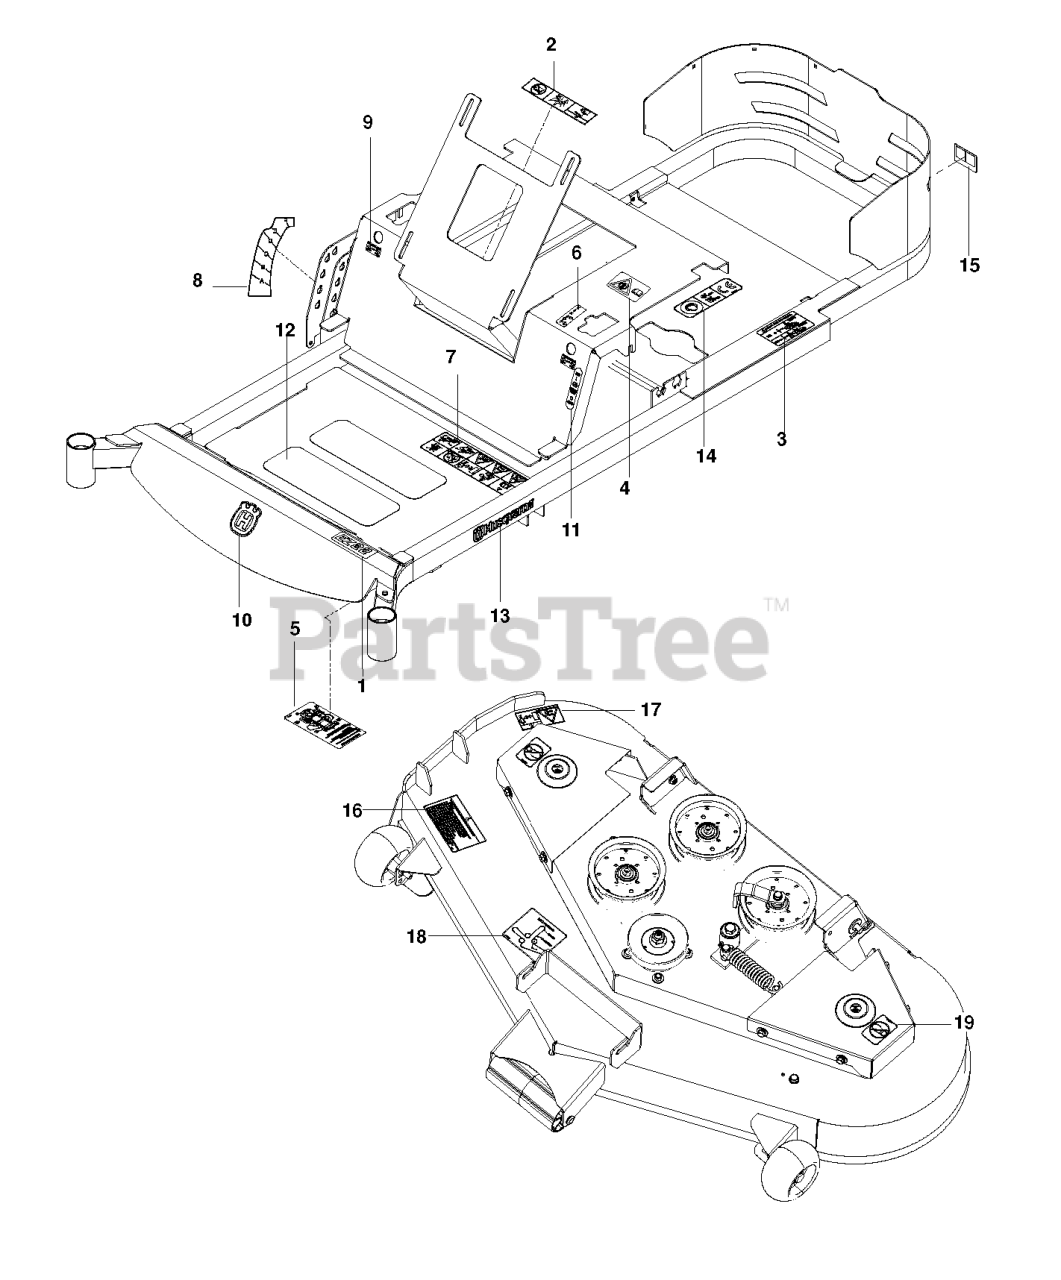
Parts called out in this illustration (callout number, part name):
1	DECAL, EZ22
2	EURO DECAL-BATTERY WARNIN6
3	DECAL, DO NOT TOW
4	DECAL, EXITING MOWER
5	DECAL, SERVICE
6	DECAL, MOTION CONTROL
7	DECAL, WARNING
8	DECAL, HEIGHT
9	DECAL, F.S.T.
10	DECAL, CROWN H 70MM
11	DECAL, PARK BRAKE
12	ANTI-SKID PAD
13	DECAL.HOOD.LOGO.ORANGE.HUSQVAR
15	DECAL
16	DECAL, DISCHARGE, MULTILINGUAL
17	DECAL, EURO SEVERING
18	DECAL, BELT ROUTING
19	DECAL, NO STEP
